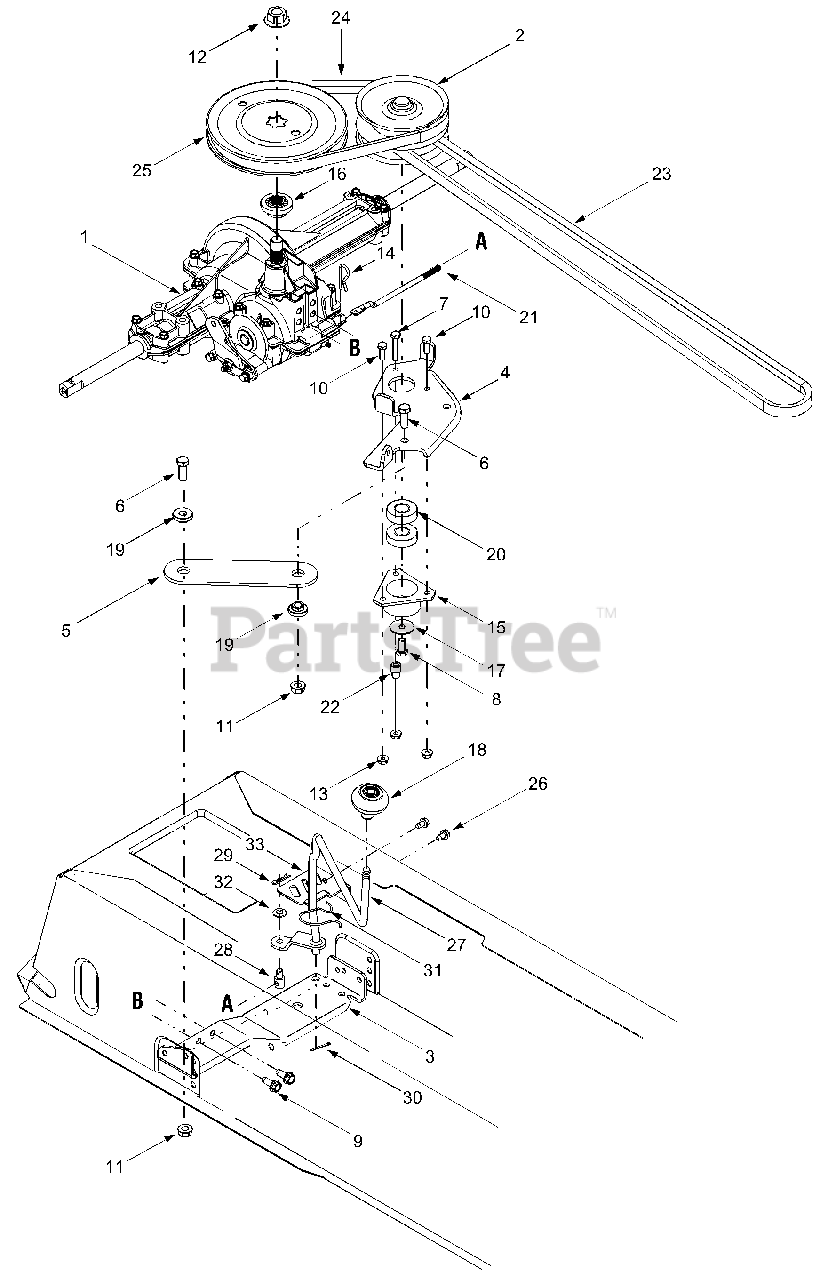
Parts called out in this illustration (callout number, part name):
1	Transmission, Single-speed
2	Variable-speed Pulley, 4.75
3	Torque Bracket
4	Variable-speed Bracket
5	Variable-speed Bracket
6	Hex Cap Screw, 3/8-16 x 1.0
7	Hex Cap Screw, 1/4-20 x 1.5
8	Hex Cap Screw, 5/16-24 x .75
9	Screw, 5/16-18 x .75
10	Hex Screw,1/4-20 x .75
11	Flange Lock Nut, 3/8-16
12	Flange Nut, 9/16-18
13	Flange Lock Nut, 1/4-20
14	Internal Cotter Pin, .125
15	Bearing Cup
16	Pulley Hub, 5/8 Spline
17	Flat Washer, .320 x 1.25 x .06
18	Shift Knob
19	Shoulder Spacer, 1.0 x .38 x .38
20	Ball Bearing, 17 x 40 x 12
21	Shift Rod
22	Stepped Spacer
23	Lower Drive Belt
24	Upper Drive Belt
25	Transmission Pulley, 7.25
26	Self-tapping Screw, 1/4-20 x .5
27	Shift Lever Assembly
28	Ferrule, 1/4-20 x 1.0
29	Cotter Pin, 1.13
30	Cotter Pin, 1.25
31	Spring Compression Clip
32	Flat Washer, .344 x .688 x .065
